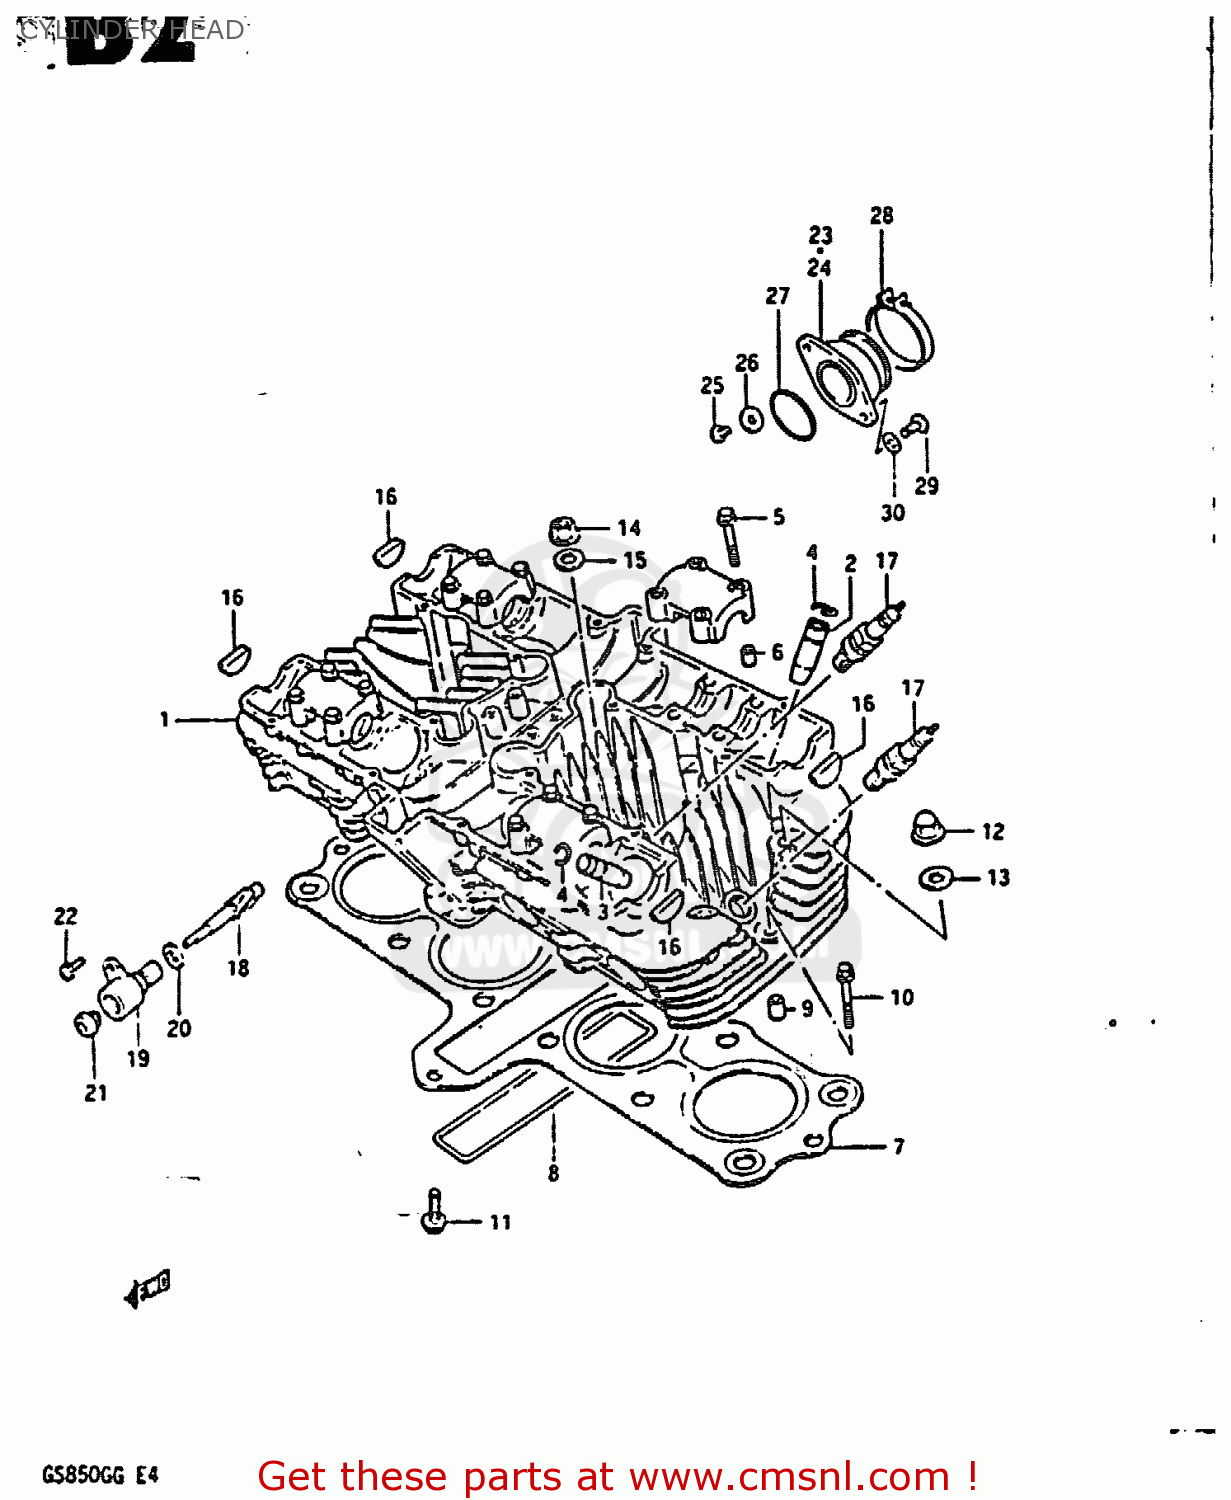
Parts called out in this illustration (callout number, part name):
1	HEAD ASSEMBLY,CYLINDER
2	GUIDE,INTAKE VALVE
3	GUIDE,EXHAUST VALVE
4	RING,SNAP
5	BOLT(6X39)
6	PIN(6.2X8X11)
7	GASKET,CYLINDER HEAD (MCA)
8	O RING(D:3,ID:26X157)
9	PIN
10	BOLT (6X45)
11	BOLT 6X30
12	NUT
13	GASKET(10.5X22X2) (NAS)
14	NUT
15	WASHER(10.5X22X2.3)
16	PLUG
17	PLUG,SPARK
18	GEAR,TACHOMETER DRIVEN
19	SLEEVE,TACHOMETER DRIVE GEAR
20	SEAL,TACHOMETER DRIVEN
21	SEAL,OIL(5X12X8)
22	SCREW(5X12)
23	PIPE,INTAKE,R
24	PIPE,INTAKE,L
25	BOLT, INTAKE PORT
26	GASKET(5.3X9.3X1.2) (NAS)
27	O RING(D:2.4,ID:37.7)
28	CLAMP
29	SCREW
30	WASHER
